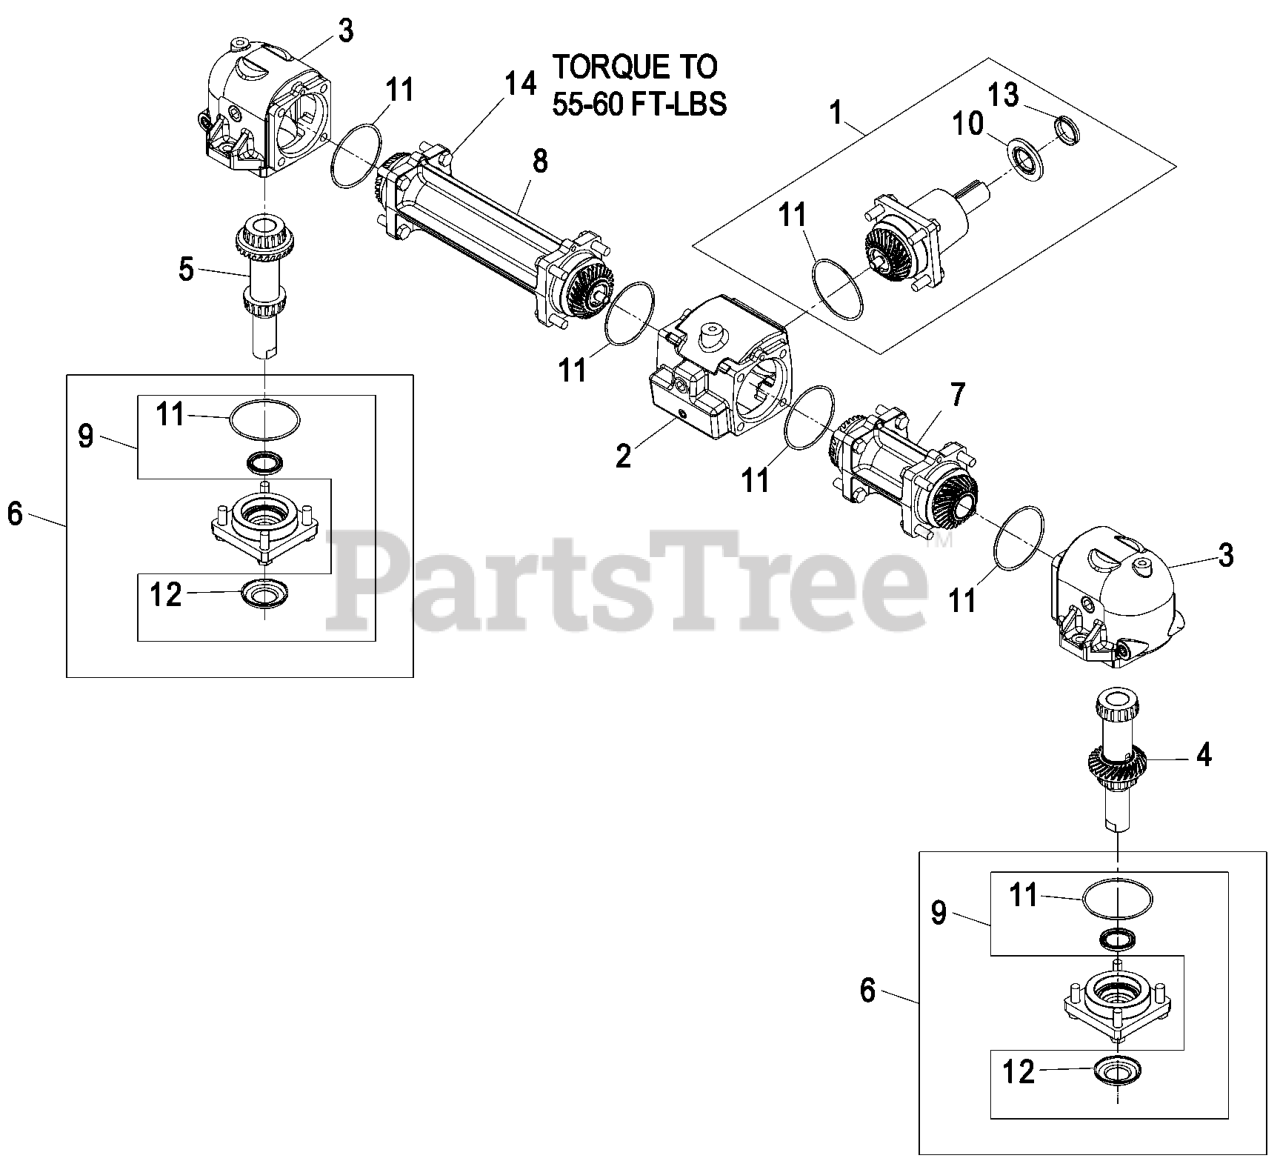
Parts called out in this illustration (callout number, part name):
1	INPUT PINION ASM
2	HOUSING-CENTER
3	HOUSING-END
4	LH OUTPUT SHAFT AND GEAR
5	RH OUTPUT SHAFT AND GEAR
6	CAP-OUTPUT
7	TUBE-CONNECTOR, SHORT
8	TUBE-CONNECTOR, LONG
9	OUTPUT SEAL KIT
10	SEAL-INPUT
11	SEAL-O-RING
12	WASHER-CUPPED
13	SEAL-V-RING
